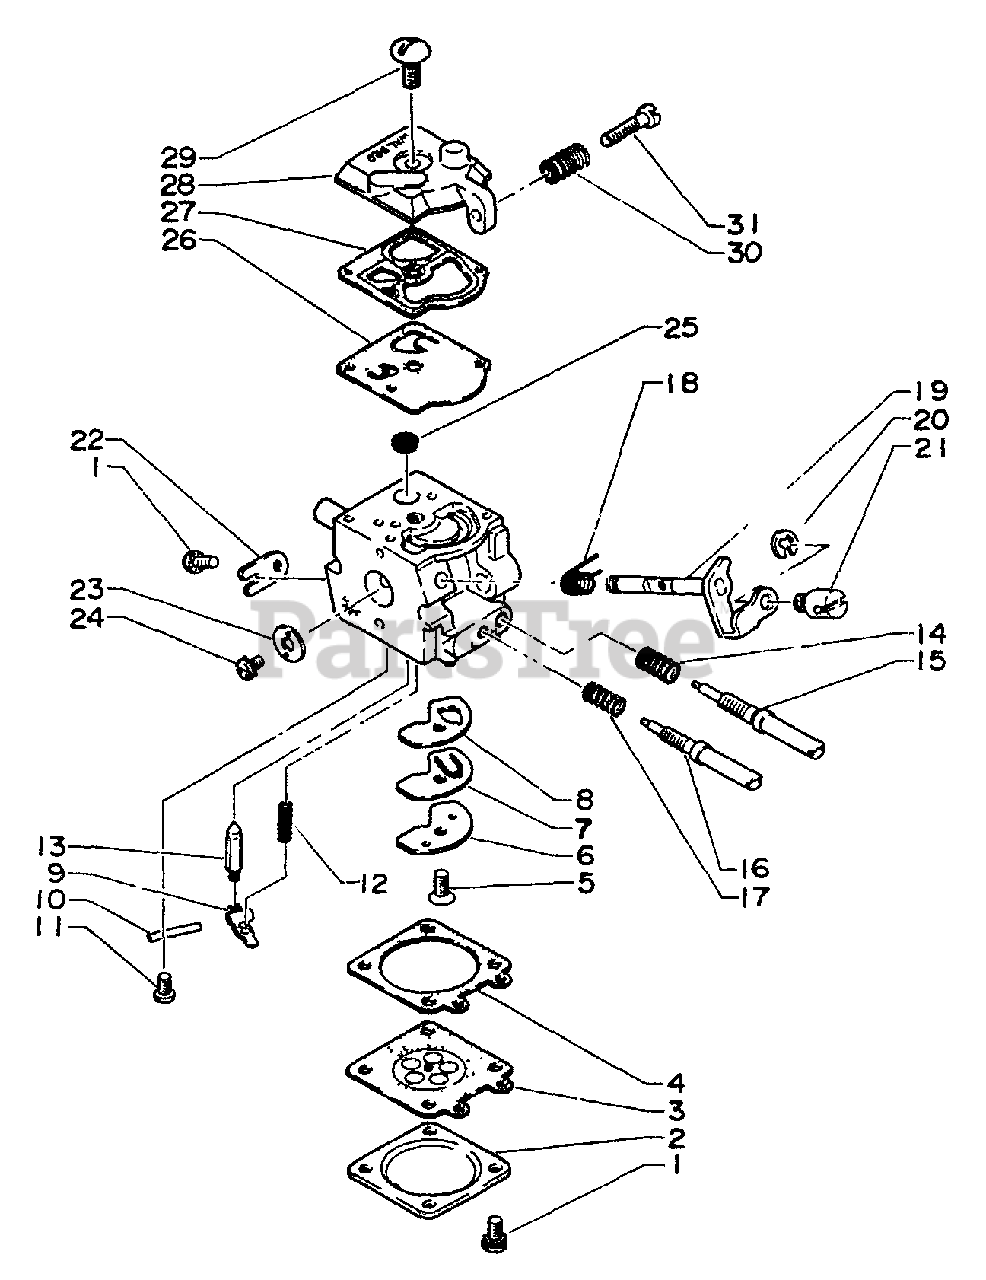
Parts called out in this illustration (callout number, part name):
2	COVER, METERING
3	DIAPHRAGM, METERING
4	GASKET, METERING
5	SCREW, CIRCUIT PLATE
6	PLATE, CIRCUIT
7	VALVE, CHECK
8	GASKET, CIRCUIT PLATE
9	LEVER, METERING
10	PIN, METERING LEVER
11	SCREW, METERING LEVER PIN
12	SPRING, METERING LEVER
13	VALVE, INLET NEEDLE
14	SPRING, IDLE ADJUST
15	NEEDLE - LOW SPEED
16	NEEDLE - HIGH SPEED
18	SPRING, THROTTLE RETURN
19	SHAFT, THROTTLE
20	RING, RETAINING
22	CLIP, THROTTLE SHAFT
23	VALVE, THROTTLE
25	STRAINER
26	DIAPHRAGM, PUMP
27	GASKET, PUMP
28	COVER, PUMP
29	SCREW, PUMP COVER
30	SPRING, IDLE ADJUST
31	SCREW, IDLE ADJUST
